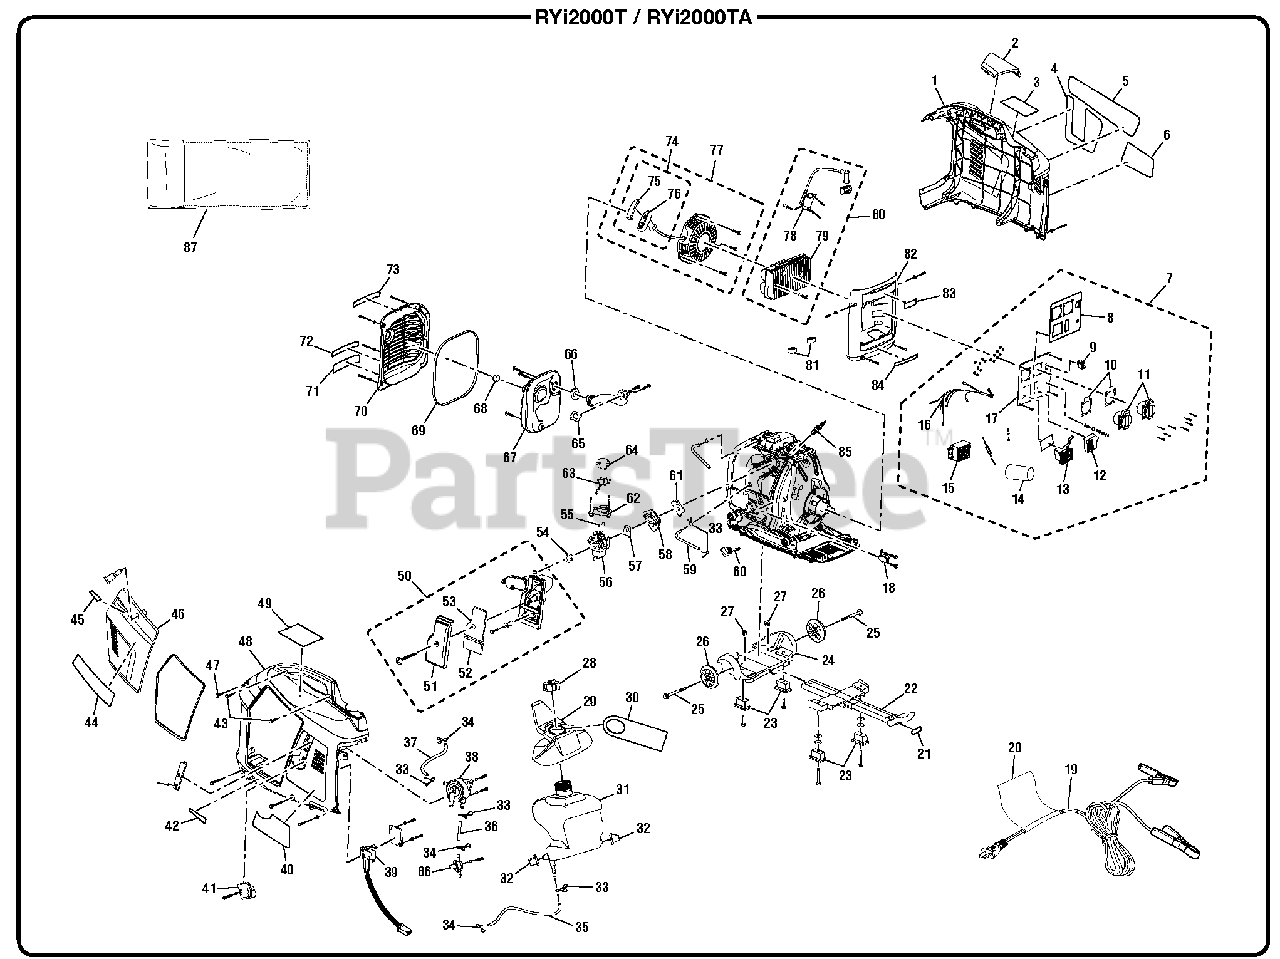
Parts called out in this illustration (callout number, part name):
1	Right Housing Assembly w/Labels
2	Spark Plug Access Cover
3	E85 Label
4	Performance Label
5	2000 Watt Inverter Label (Left)
6	Features Label
7	Control Panel Assembly
8	Control Panel Label
9	Auto Idle Switch
10	AC Receptacle Insulator
11	AC Receptacle (120 Volt)
12	Ignition Module
13	DC Receptacle
14	Heat Shrink Tube
15	Bridge Rectifier
16	Wiring Harness (Internal)
17	Control Panel
18	Pick-Up Coil
19	Battery Charging Cable
20	Cord Label
21	Handle Release Label
22	Handle Assembly
23	Rubber Foot
24	Rear Handle and Wheel Bracket
25	Wheel Mounting Bolt
27	Hex Nut (Wheel Mounting)
28	Fuel Cap Assembly
29	Fuel Overspill Guard
30	Hangtag (Warning)
31	Fuel Tank
32	Fuel Tank Support
33	Clamp (D9 x 1.2 mm)
34	Clamp (D7 x 0.8 mm)
35	Fuel Line (D4 x D8 x 260 mm)
36	Fuel Line (D4 x D8 x 130 mm)
37	Fuel Line (D4 x D8 x 170 mm)
38	Fuel Pump
39	Engine Shut Off Switch
40	Quick Start Label
41	Switch Handle
42	Lubricant Label
43	Bolt (M6 x 30 mm)
44	2000 Watt Inverter Label (Right)
45	Choke Label
46	Maintenance Cover w/Labels
47	Bolt (M6 x 100 mm)
48	Left Housing Assembly w/Labels
49	CPSC Label
50	Air Filter Assembly
51	Air Filter Cover
52	Air Filter (Lower)
53	Air Filter (Upper)
54	Intake Gasket
55	Governor Damping Spring
56	Carburetor Assembly
57	Carburetor Gasket
58	Heat Dam Insulator
59	Pulse Line (D7 x D11 x 160 mm)
61	Insulator Gasket
62	Governor Bottom Cover
64	Governor Top Cover
65	Manifold Gasket
66	Muffler Gasket
68	Spark Arrestor
69	Muffler Cover Seal
70	Muffler Cover w/Labels
71	Data Label
72	Combustion Label
73	Hot Surface Label
74	Rope Handle Assembly
75	Handle Cover (Rope)
76	Rope Handle
77	Recoil Starter Assembly
78	Ignition Coil
79	Inverter Module
80	Inverter Module w/Ignition Coil
81	Inverter Module Support
82	Control Panel Holder
83	Logo Label (Small)
84	Ground Warning Label
85	Spark Plug
86	Fuel Shut Off Valve
